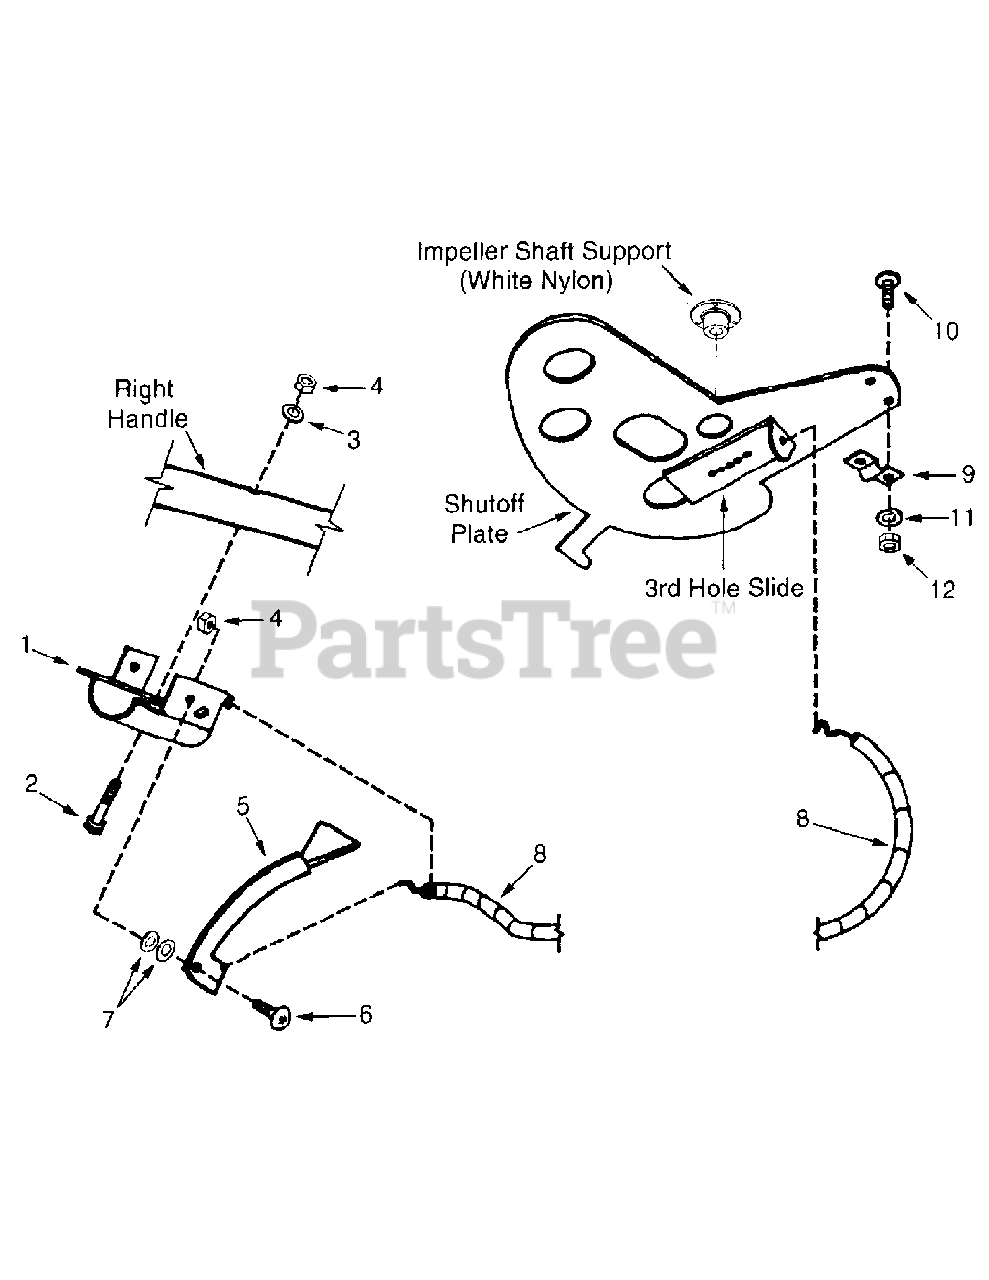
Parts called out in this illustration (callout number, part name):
1	Bracket, Dual Lever
2	Machine Screw
3	Flat Washer 1/4
4	Hex Nut, 1/4-20 Nylock
5	Lever, Dual Remote
6	Machine Screw
7	Flat Washer, 1/4 Nylon
8	Control Cable
9	Cable Clamp
10	Machine Screw
11	Lock Washer #8
12	Hex Nut, #8-32
